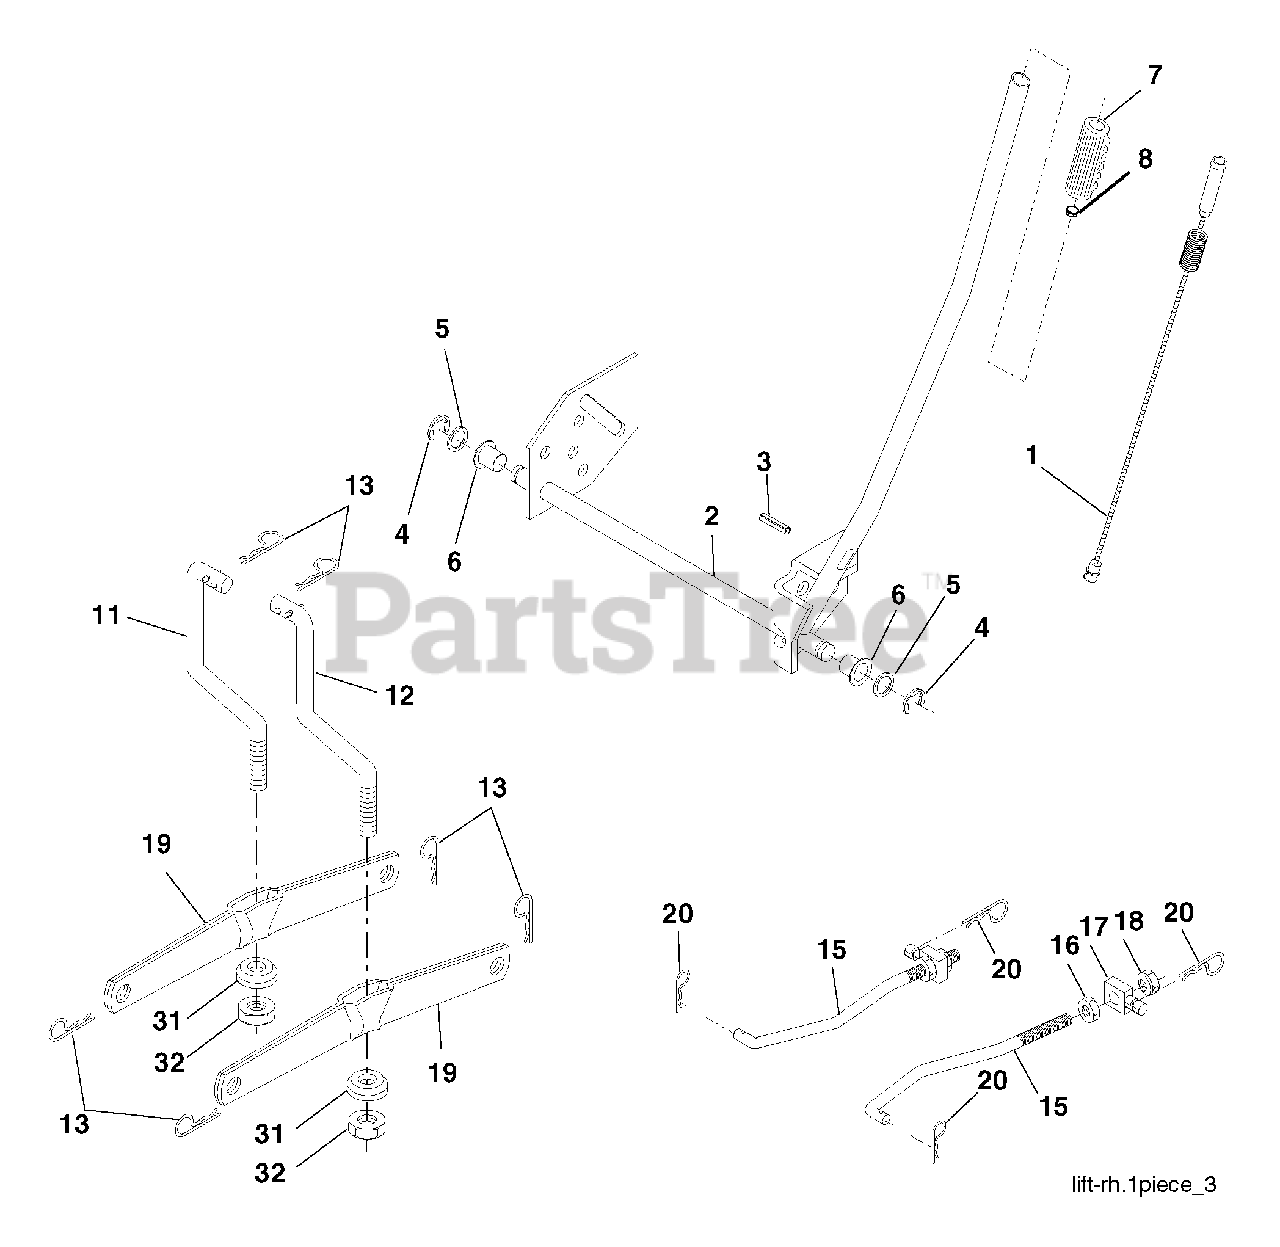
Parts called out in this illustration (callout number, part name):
1	Plunger Asm.
2	Shaft Asm Lift RH w/Inf
3	Pin Groove
4	E Ring #5133-62
5	Washer 21/32 x 1 x 21 Ga.
6	Bearing Nylon Blk 629 Id
7	Grip Handle
8	Button Plunger
11	Link Lift LH Fixed Length
12	Link Lift RH Fixed Length
13	Retainer Spring
15	Link Front
16	Nut Jam Hex 1/2-13 unc
18	Nut Lock W/Wsh 1/2-13 unc
19	Arm Suspension Rear
20	Retainer Spring
31	Bearing Pvt Lift
32	Nut Crownlock 3/8 - 24
